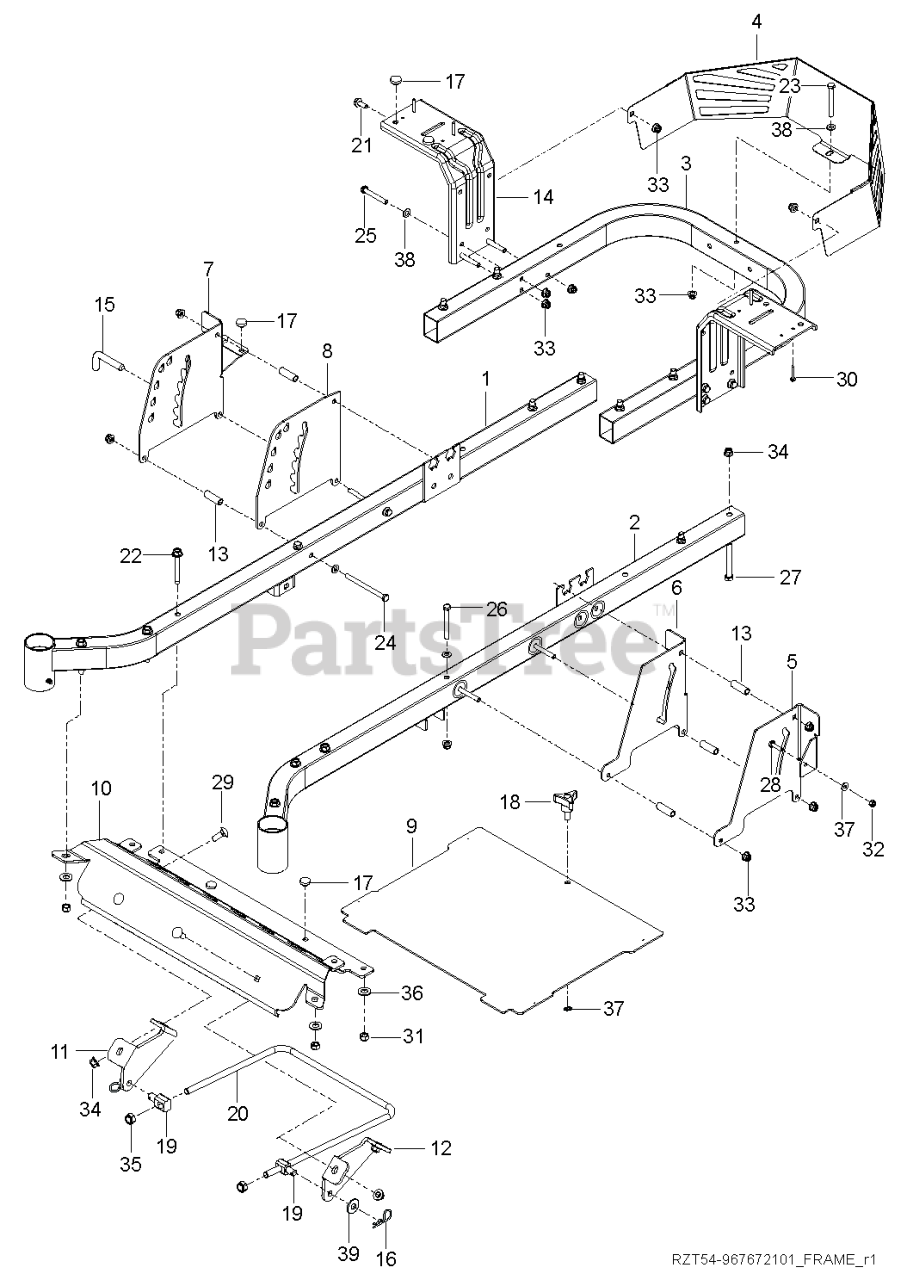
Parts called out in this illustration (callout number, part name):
1	FRAME TUBE RZ MAIN WELDMENT RI
2	FRAME TUBE RZ MAIN WELDMENT LE
3	FRAME REAR TUBE SNAPPER RED X6
4	GUARD HEAT SHIELD,RZ,21IN FRAM
5	PLATE, OUTER BRAKE, BLACK
6	PLATE, BRAKE LATCH, BLACK
7	PLATE.DECK HEIGHT.PNT.431.RZ
8	PLATE, DECK HEIGHT, BLACK
9	KIT.PLATE.FLOOR.W/DCL.REDM.672
10	FOOT REST, MED BLK
11	MOUNT.STRUT.RH.431
12	MOUNT.STRUT.LH.431
13	SPACER.334.ID.5.OD.1.5.L
14	FENDER.SUPPORT.PNT.X431
15	PIN.DECK.HEIGHT.RZ
16	HAIRPIN #4
17	GROMMET, BUMPER
18	KNOB W/STUD
19	SWIVEL.TRUNION.LINK.DECK.FRONT
20	RHSNB 3/8C X 1
21	HHFS 5/16-18 X 3/4
22	HHFS 3/8-16 X 3 GRD 5 ZD
23	BOLT HEX FLGHD 5/16-18X3 GR. 5
24	HCS 5/16C X 4
25	BOLT.FIN HEX 5/16-18UNC X2 1/4
26	BOLT HEX
27	BOLT.HEX.FIN.3/8-16 X 3.GR5
29	SCR #10-12X1-1/2HEX WASH HD ZD
30	NUT 3/8-16 HEX FLG NYLOC ZD
31	NUT HEX 3/8-16 NYLON, THIN
32	RP_NUT 1/4-20 NYLOC
33	5/16-18 NYLOC FLANGE NUT
34	WASHER
35	WASHER 3/8 FLAT
36	WASHER
37	WASHER 5/16"
